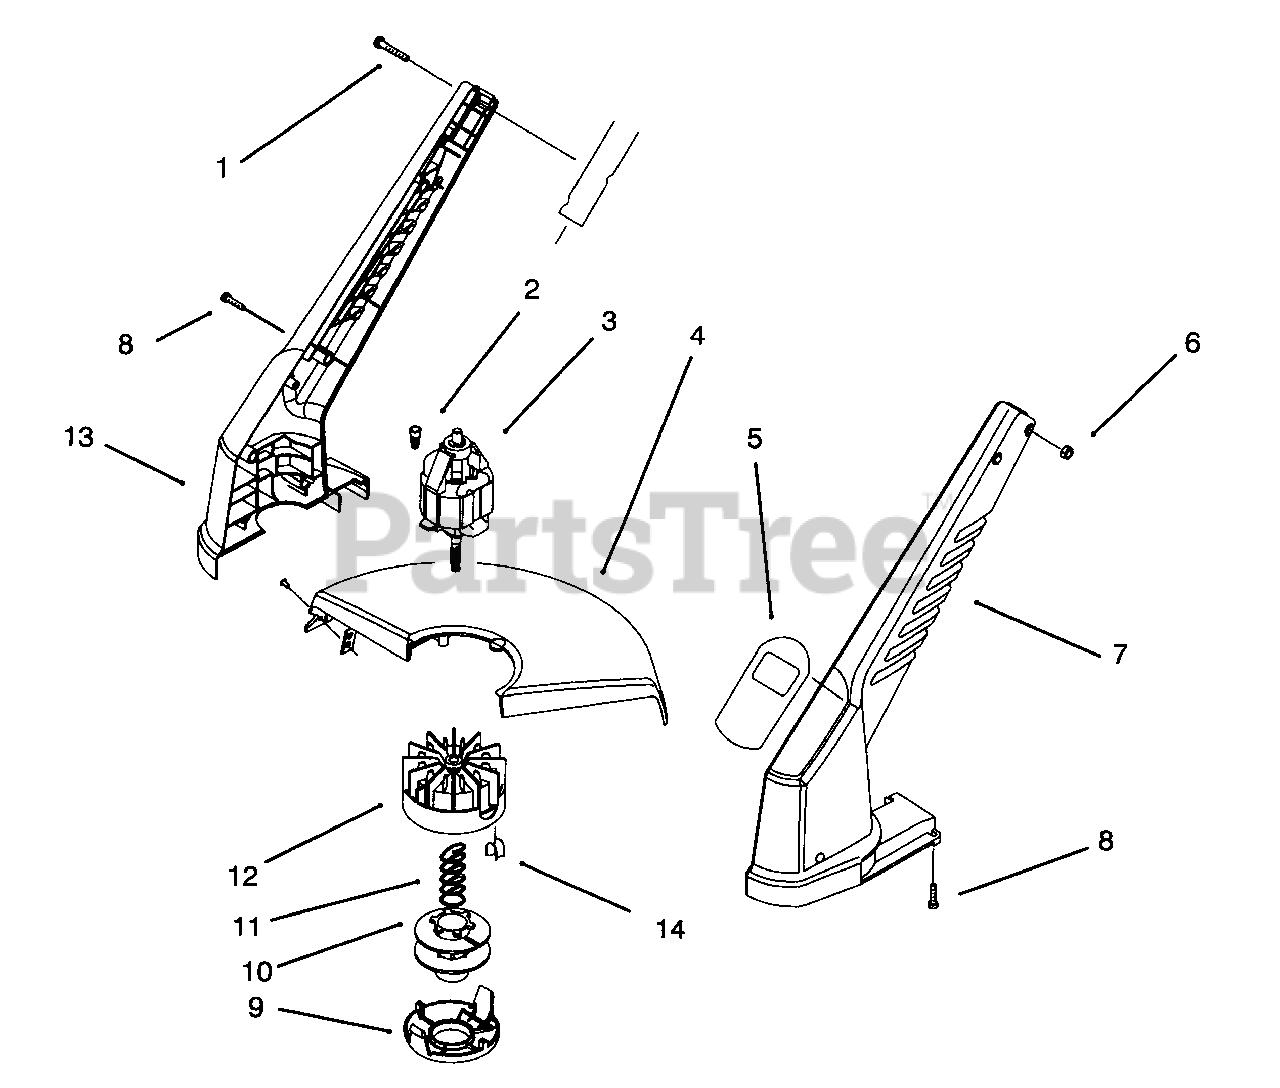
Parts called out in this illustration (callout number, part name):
1	Screw-Pan Hd.
2	Connector-Wire Nut
3	Motor Assembly (Incl. Ref.#12 & 14)
4	Shield-14"
5	Decal-14" Trimmer
7	Housing L.H.
8	Screw-Pan Hd. Tapping
12	Drum
13	Housing R.H.
